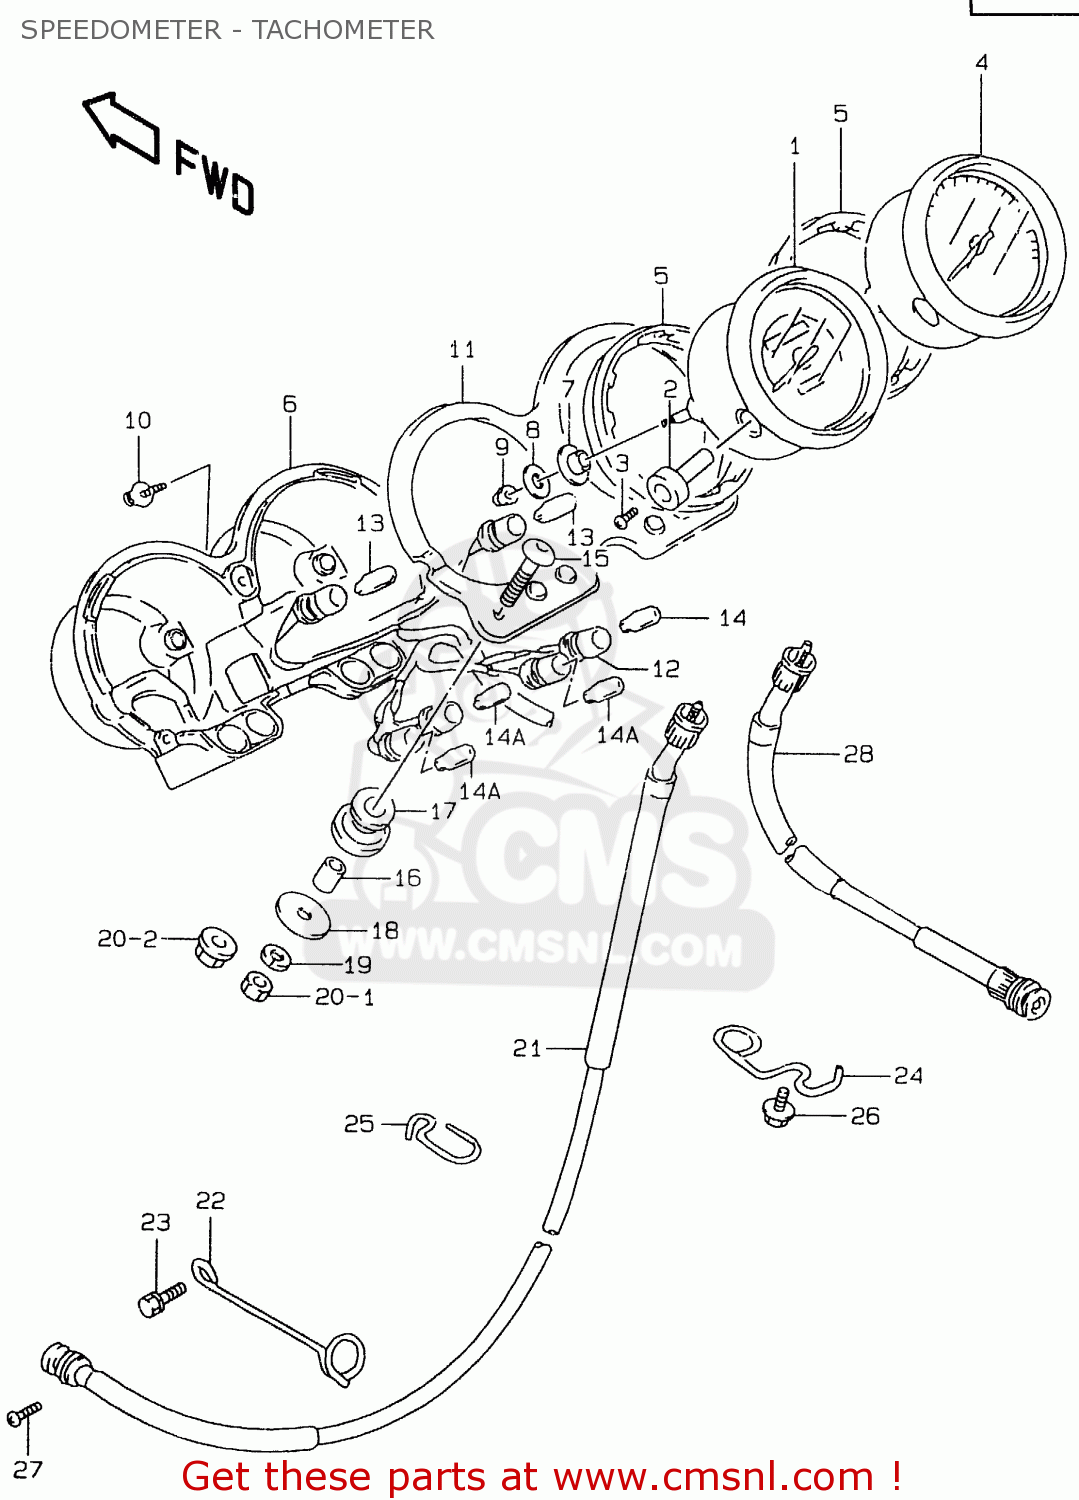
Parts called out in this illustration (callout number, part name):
1	SPEEDOMETER(MILE/KILO)
2	KNOB,TRIP
3	SCREW(2X6)
4	TACHOMETER
5	DAMPER
6	COVER
7	CUSHION
8	WASHER(5.5X16X1.2)
9	NUT
10	SCREW
11	BRACKET,METER
12	SOCKET
13	BULB(12V3.4W,T10)
14	BULB(12V1.7W,T10)
14A	BULB(12V3.4W,T10,BF175-01450A)
15	BOLT(6X30)
16	SPACER(6.5X10X15.7)
17	CUSHION,METER BRACKET
18	WASHER(6.5X28X1.6)
19	LOCK WASHER
20	NUT
21	CABLE ASSY,SPEEDOMETER
22	CLAMP,SPEEDOMETER CABLE
23	BOLT
24	GUIDE,SPEEDOMETER CABLE NO.2
25	GUIDE,SPEEDOMETER CABLE NO.3
26	BOLT
27	SCREW
28	CABLE ASSY,TACHOMETER
